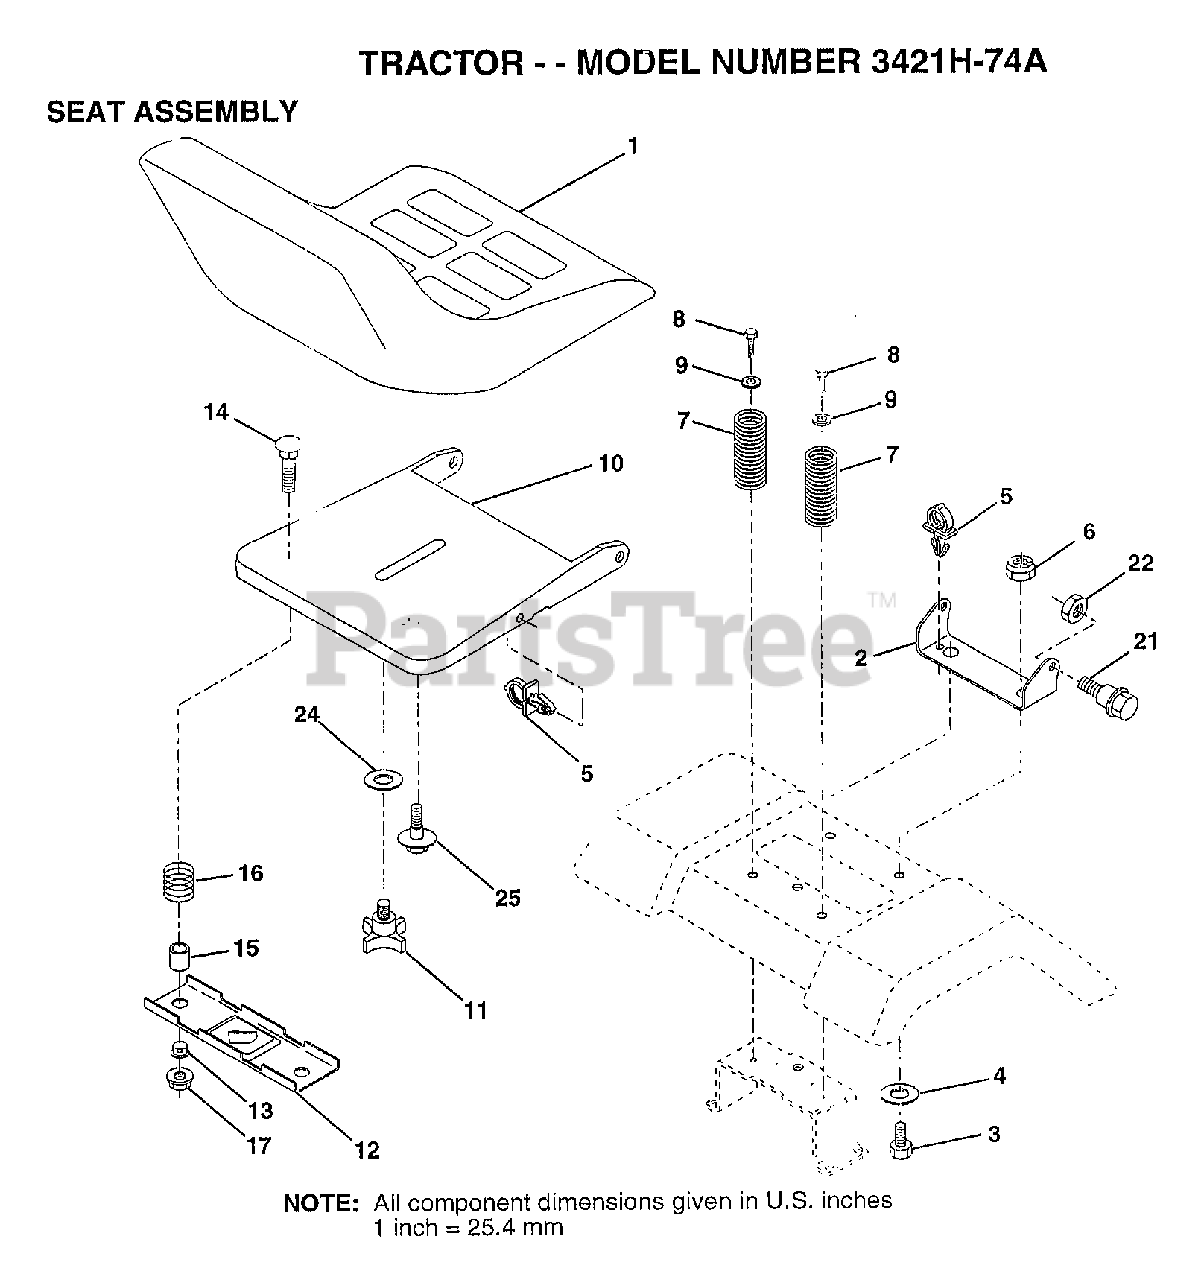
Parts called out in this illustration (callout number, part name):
2	BRACKET PVT SEAT
3	BOLT
4	WASHER PM
5	CLIP.PUSH-IN.HING
6	NUT
7	SPRING COMPRESSIO
8	SCREW GTV
9	WASHER
10	PAN-SEAT
11	"KNOB 1/2"" YT"
12	BRKT SWITCH
13	BUSHING
15	SPACER SPLIT
16	SPRING COMPRESSED
21	"BOLT,SHOULDER"
24	WASHER
25	"BOLT,SHOULDER"
